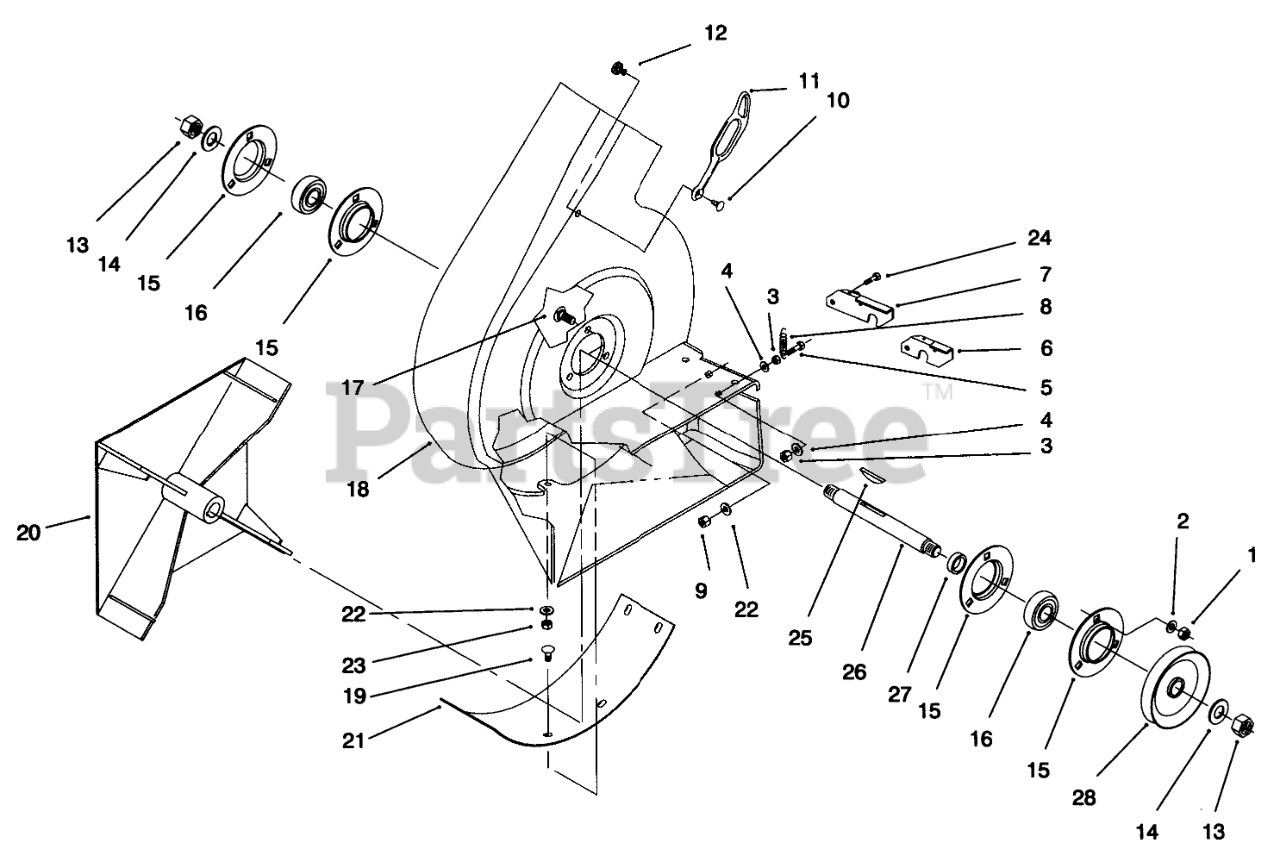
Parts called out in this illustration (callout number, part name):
1	NUT-HEX
2	WASHER-LOCK
3	NUT-HEX
4	WASHER-FLAT
5	SCREW-HWH
6	42" BLOWER LATCH B
7	48" BLOWER LATCH B
8	SPRING-EXTENSION
9	NUT-LOCK, NI
10	FASTENER-PANEL
11	RETAINER-DUCT
12	SPACER-INTERLOCK
13	NUT-JAM
14	WASHER-LOCK
15	FLANGE
16	BEARING-BALL
17	SCREW-CARR
18	HOUSING-VAC, BLOWER
19	SCREW-CARRIAGE
20	Impeller
21	COVER-BLOWER, BOTTOM
22	WASHER-FLAT
23	NUT-LOCK, NI
24	SCREW-HH
26	SHAFT-BLOWER
27	Spacer
28	PULLEY-BLOWER
